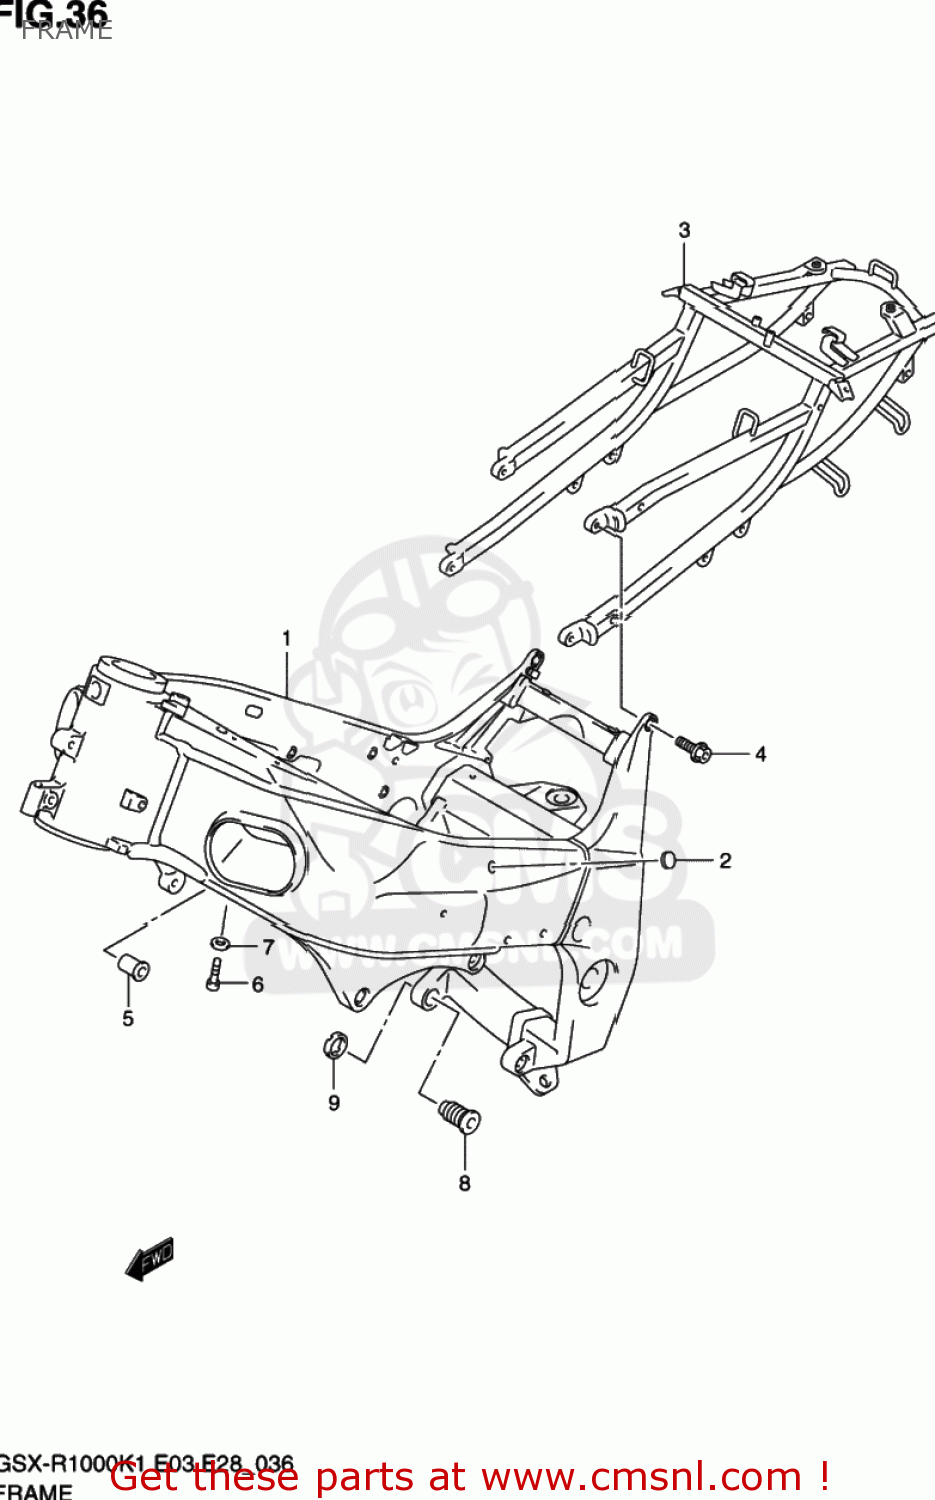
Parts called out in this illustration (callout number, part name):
1	FRAME COMP
2	CAP,TANK RAIL
3	RAIL,SEAT
4	BOLT,SEAT RAIL
5	SPACER,ENGINE MOUNTING
6	BOLT
7	WASHER
8	BOLT,CRANK CASE ADJUST
9	NUT,CRANK CASE ADJUST BOLT
